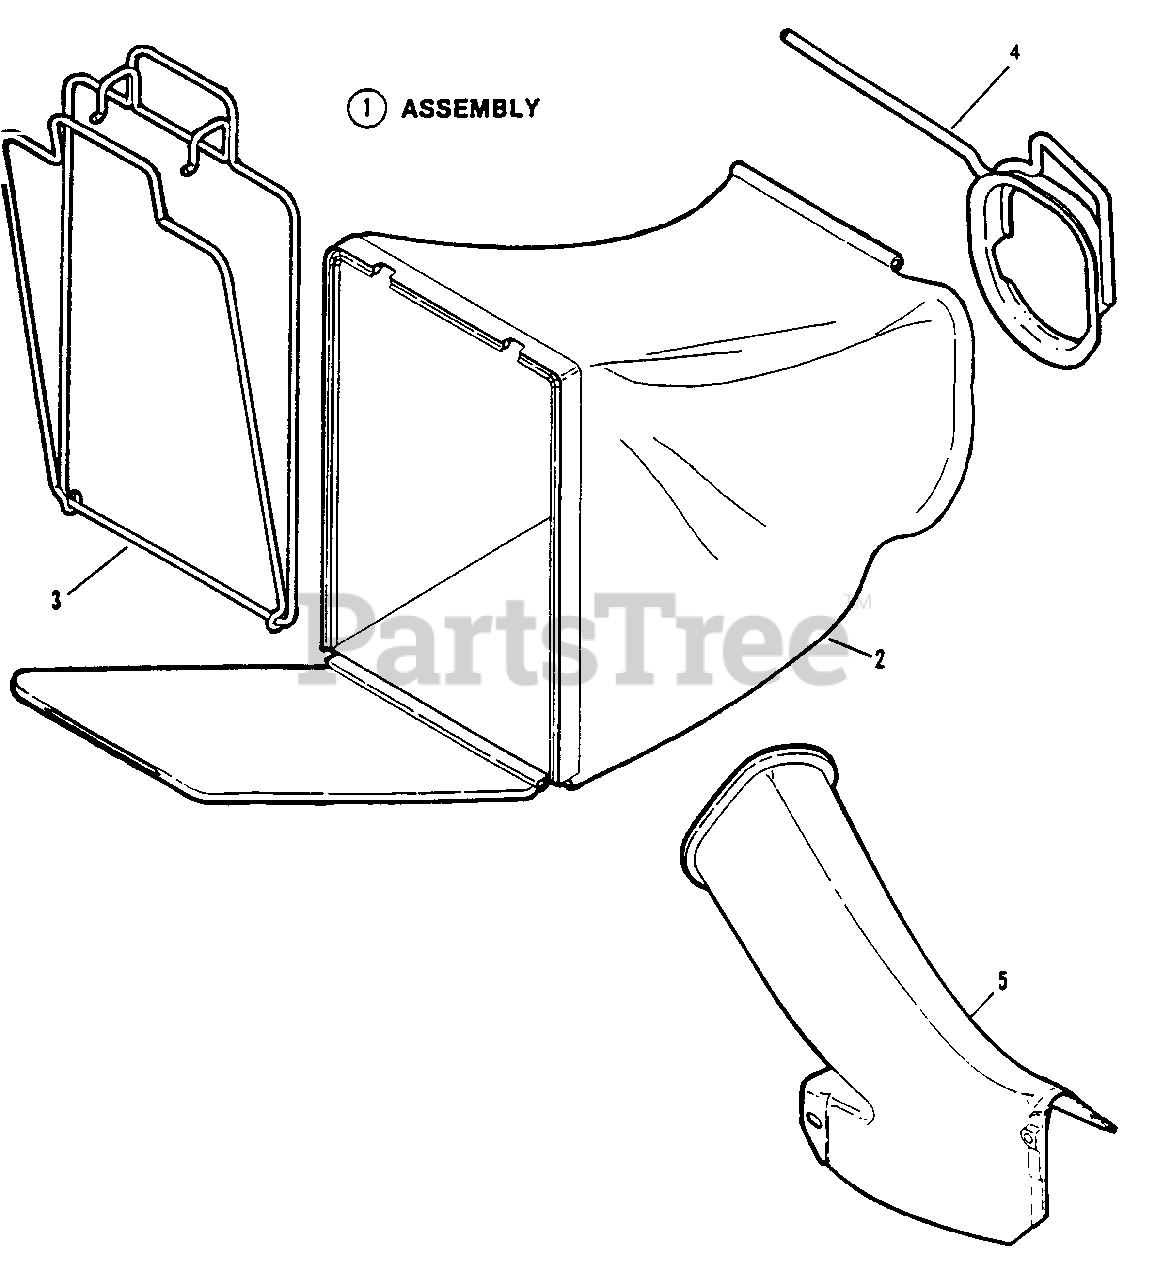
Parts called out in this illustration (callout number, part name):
1	ASSEMBLY, Grass Bag
2	BAG, Door Type (Wide) (Black)
3	ASSEMBLY, Bag Wire
4	CONNECTOR, Grass Bag
5	ADAPTER, Bag
